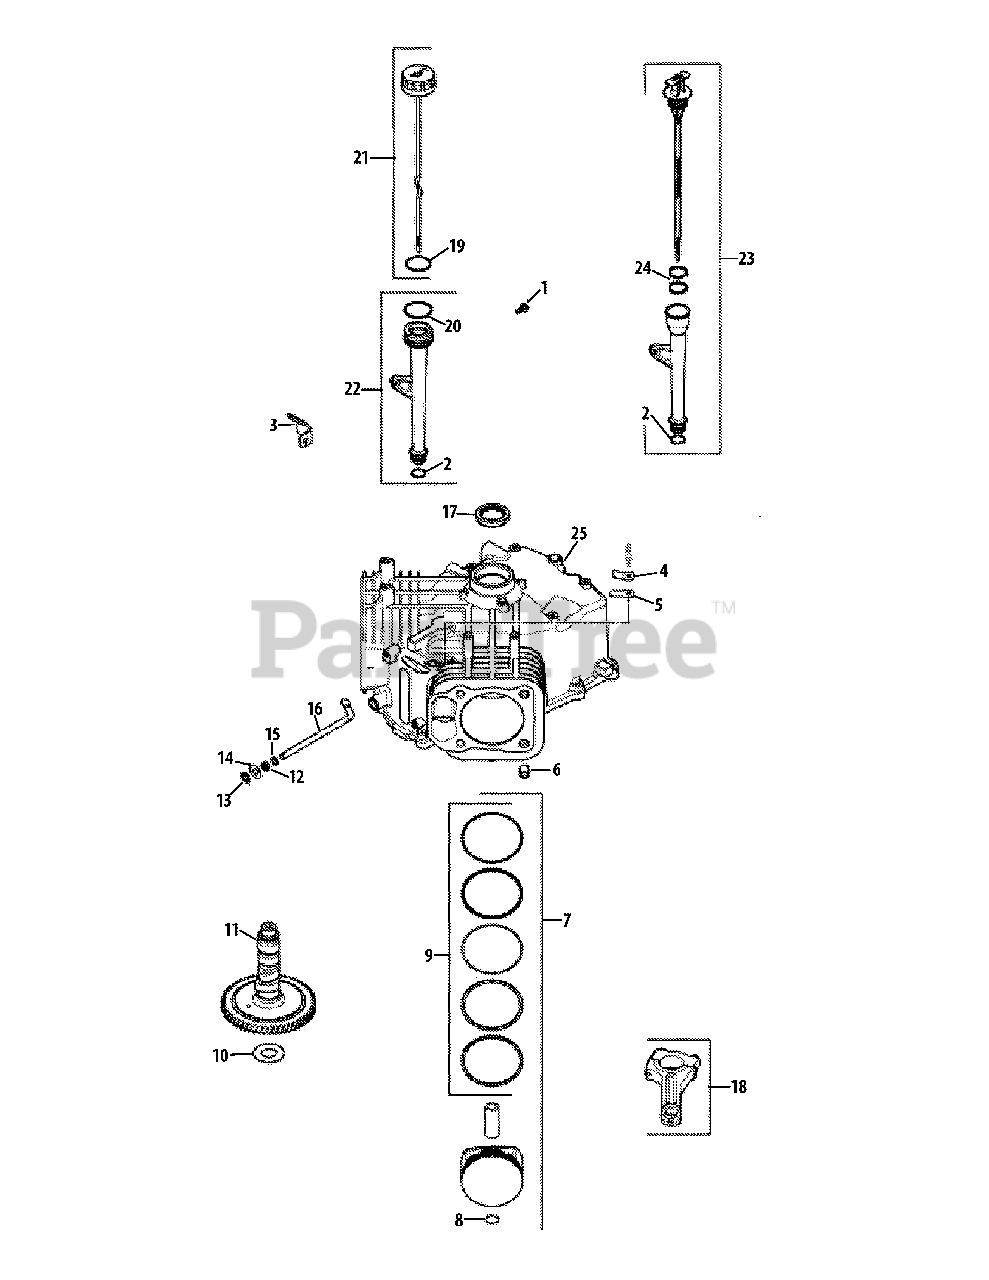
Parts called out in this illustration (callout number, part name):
1	Flange Screw, M5 x .8 x 13
2	Lower Oil Fill Tube O-Ring
3	Oil Fill Tube Bracket
4	Breather Reed Retainer
5	Breather Reed
7	Piston w/ Ring Set Kit (Inc. #8 & 9)
8	Piston Pin Retainer
9	Ring Set (.08)
9	Ring Set (STD)
9	Ring Set (.25)
10	Camshaft Shim (White, .028)
10	Camshaft Shim (Blue, .03)
10	Camshaft Shim (Red, .032)
10	Camshaft Shim (Yellow, .034)
10	Camshaft Shim (Green, .036)
10	Camshaft Shim (Gray, .038)
10	Camshaft Shim (Black, .04)
11	Camshaft Kit (Inc. KH-25-357-14-S)
12	Governor Cross Shaft Seal
13	Ring Retainer
14	Flat Washer, 9mm
15	Flat Washer, 11.32
16	Governor Cross Shaft
17	Oil Seal, 1.78 x 1.26
18	Connecting Rod (STD)
19	Dipstick O-Ring
20	Upper Oil Fill Tube O-Ring
21	Dipstick Assembly
22	Tube Assembly
23	Dipstick & Tube Kit
24	O-Ring
25	Crankcase (Use Short Block)
